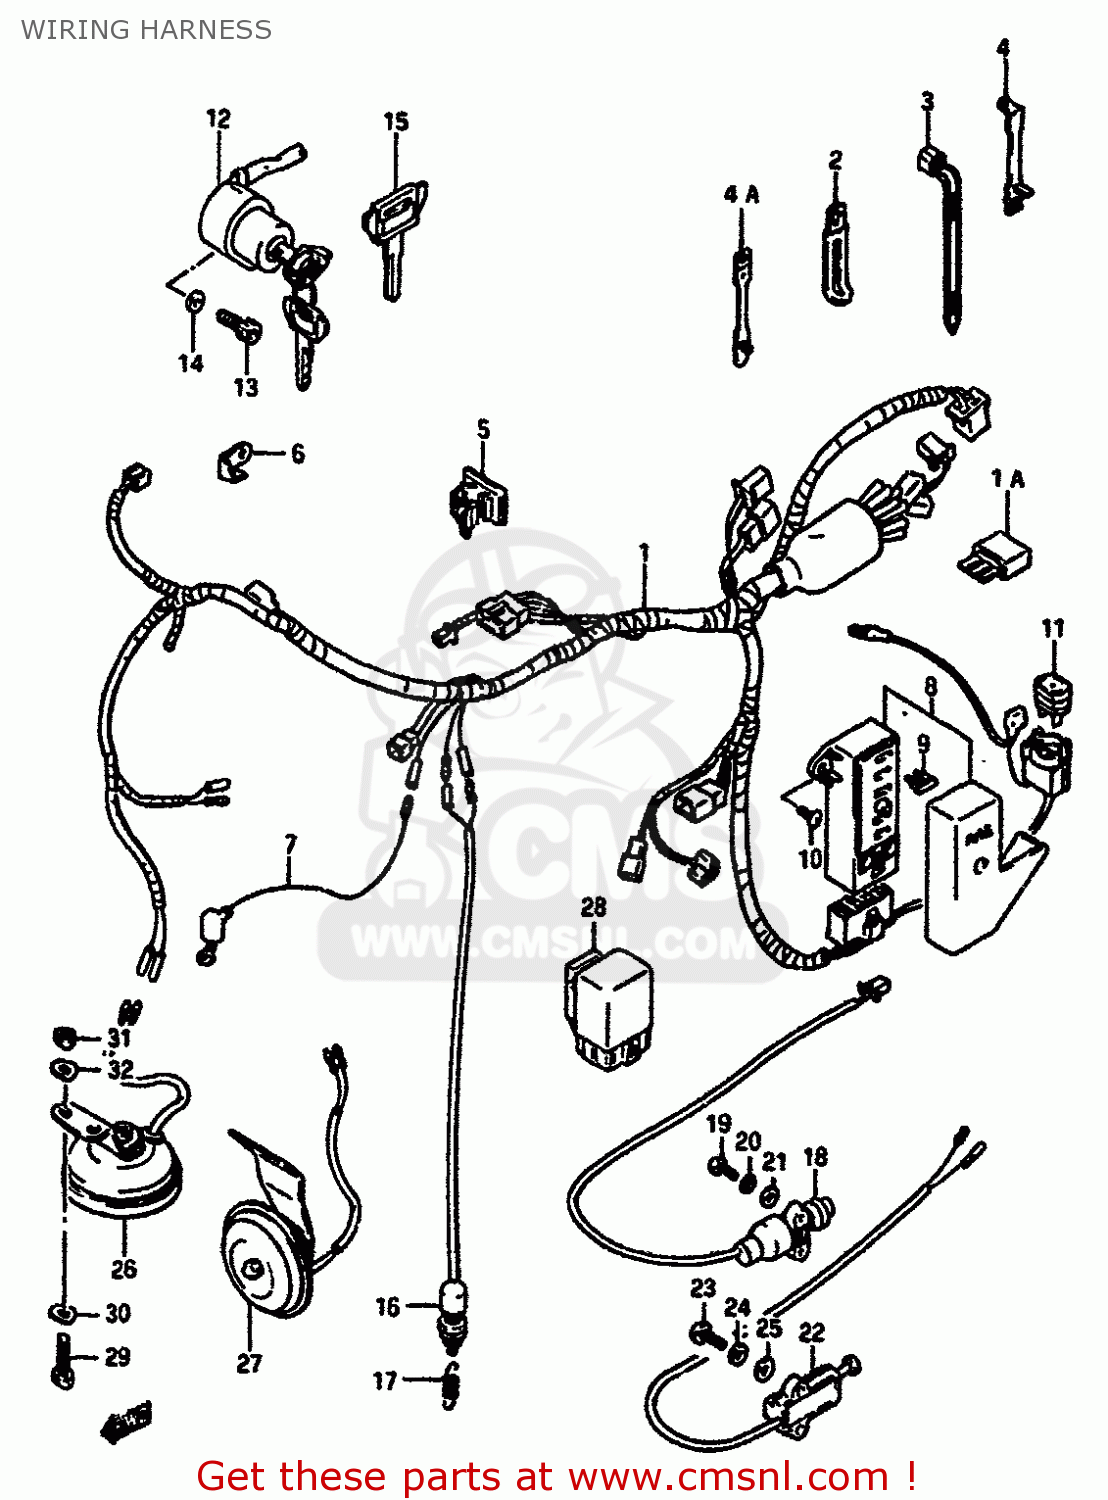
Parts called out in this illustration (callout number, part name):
1	HARNESS,WIRING
1A	DIODE(STANLEY DE8804)
2	CLAMP
3	CLAMP(L:125)
4	CLAMP(L:55)
4A	CLAMP,L:88
5	CLAMP
6	PLATE,COUPLER HOLDER
7	WIRE,WATER TEMPERATURE GAUGE
8	BOX ASSY,FUSE
9	FUSE(10A)
10	SCREW
11	BREAKER ASSY,CIRCUT
12	SWITCH ASSEMBLY,IGNITION
13	BOLT
14	LOCK WASHER
15	KEY,BLANK(TYPE:C)
16	SWITCH ASSY,STOP LAMP
17	SPRING
18	SWITCH ASSEMBLY,SIDE STAND
19	SCREW
20	WASHER,LOCK
21	WASHER,5MM
22	SWITCH ASSEMBLY,SIDE STAND
23	SCREW
24	WASHER,LOCK
25	WASHER
26	HORN ASSY
27	HORN ASSY
28	RELAY ASSEMBLY
29	BOLT 6X30
30	WASHER
31	NUT 6MM
32	WASHER
